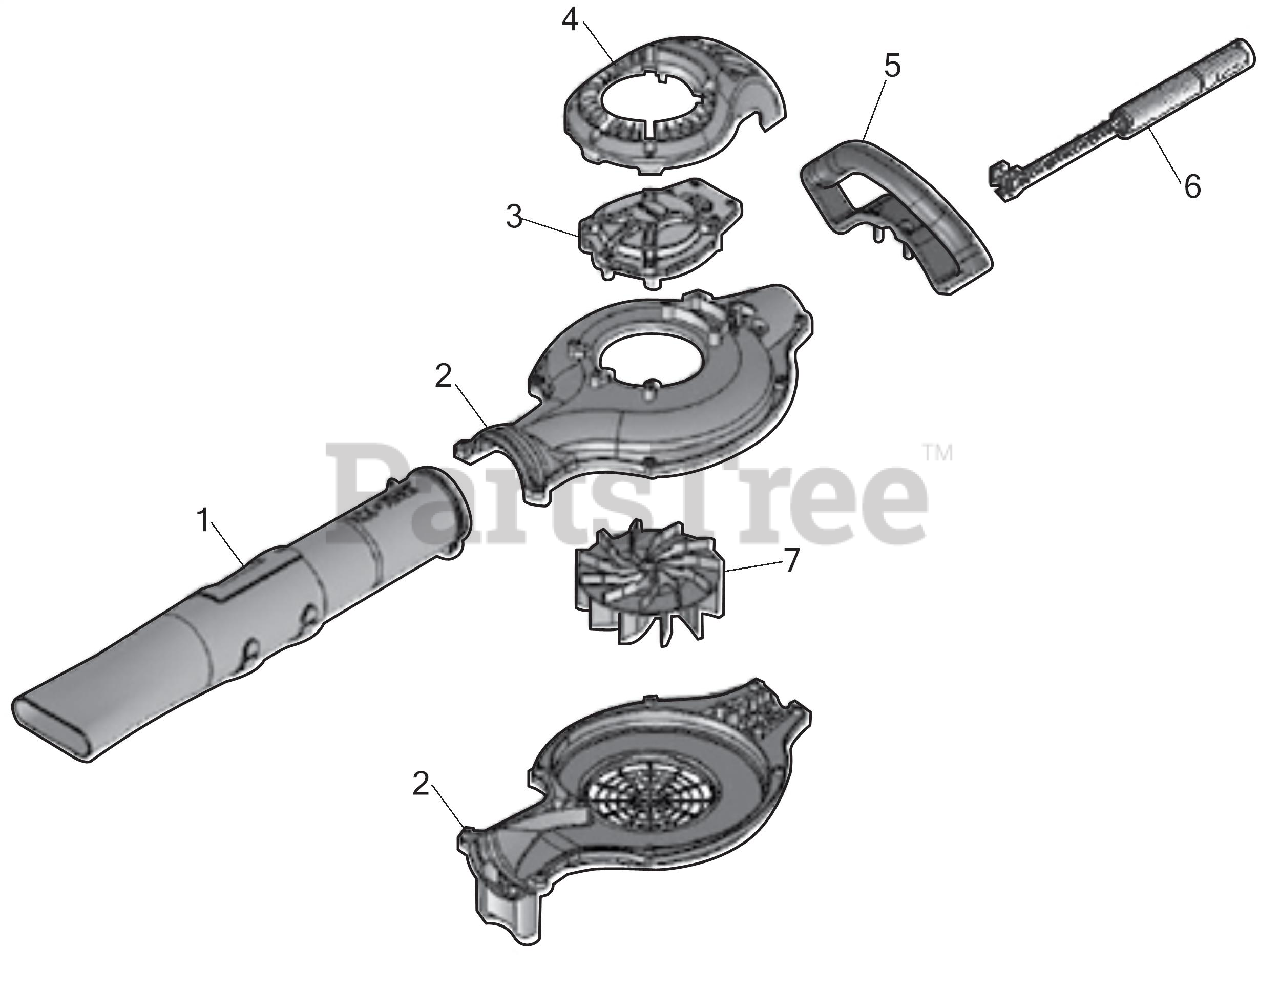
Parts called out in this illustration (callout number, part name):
1	TUBE ASSEMBLY CPL420 CORE
2	BLOWER HOUSING ASSEMBLY
3	MOTOR ASSEMBLY BLOWER CPL420
4	BLOWER COVER ASSEMBLY
5	HANDLE ASSEMBLY CORE
6	TUBE/WIRE ASSEMBLY CPL420
7	BLOWER IMPELLER ASSEMBLY
